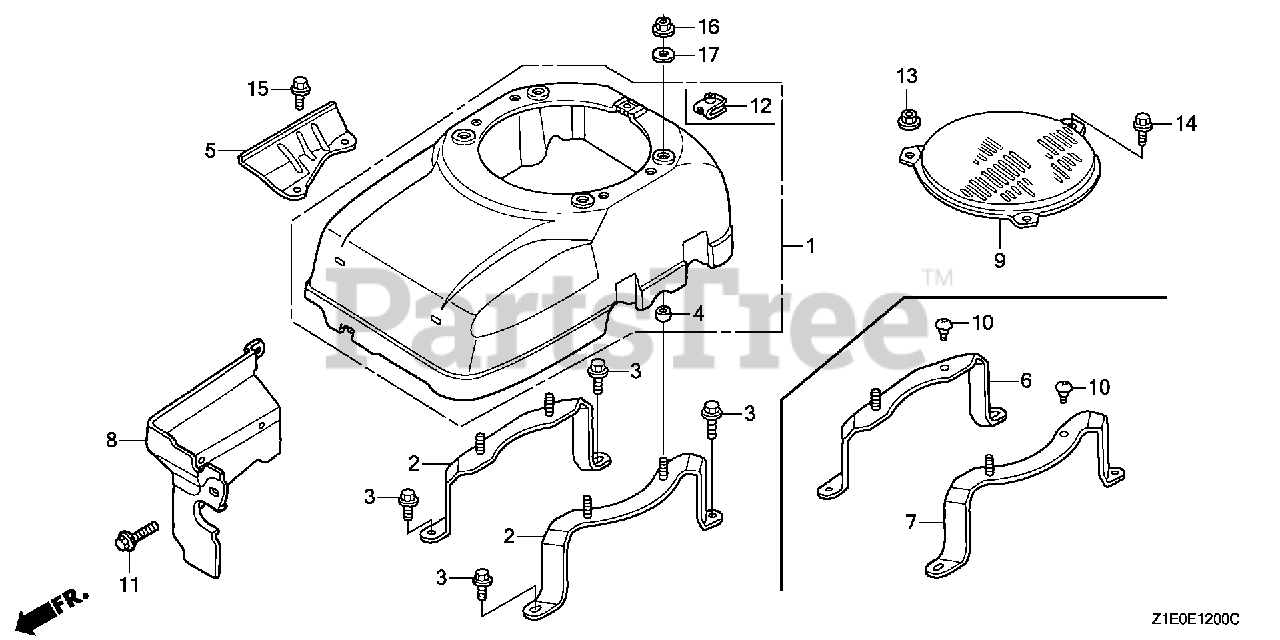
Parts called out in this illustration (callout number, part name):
1	COVER, FAN *NH1* (BLACK)
1	COVER, FAN *R280* (POWER RED)
2	BRACKET, FAN COVER
3	BOLT, FLANGE (6X16)
4	COLLAR, FAN COVER
